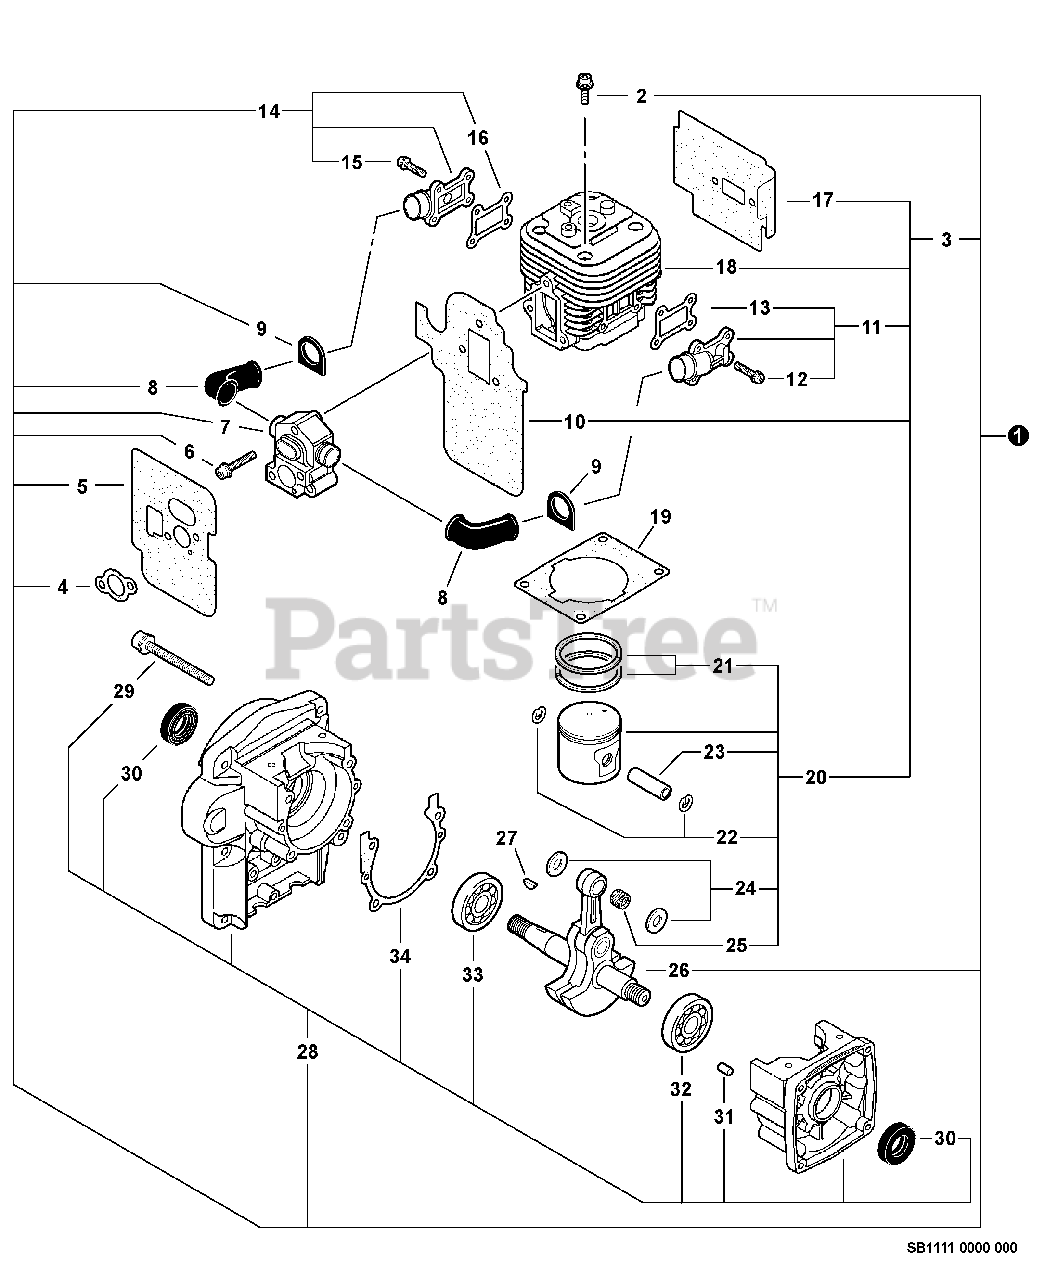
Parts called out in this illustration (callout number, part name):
1	SHORT BLOCK PB-500 & EB508RT
2	BOLT 5×22
3	CYLINDER/PISTON KIT
4	GASKET, INTAKE
5	GASKET, INTAKE
7	INSULATOR
8	HOSE, AIR
9	GROMMET
10	GASKET, INTAKE
11	REED VALVE KIT (S)
13	GASKET, INTAKE
14	REED VALVE KIT (M)
16	GASKET, INTAKE
17	HEAT SHIELD, EXHAUST
18	CYLINDER
19	GASKET, CYLINDER
20	PISTON KIT
21	RING, PISTON
22	RING, SNAP Ø10
23	PIN, PISTON
24	WASHER, THRUST 10
25	BEARING, NEEDLE 10
26	CRANKSHAFT ASSY
27	KEY, WOODRUFF 3×14
28	CRANKCASE ASSY
29	BOLT 5×40
30	SEAL, OIL
31	PIN, LOCATING 4×8
32	BEARING, BALL 6202
33	BEARING, BALL 6302 C3
34	GASKET, CRANKCASE
